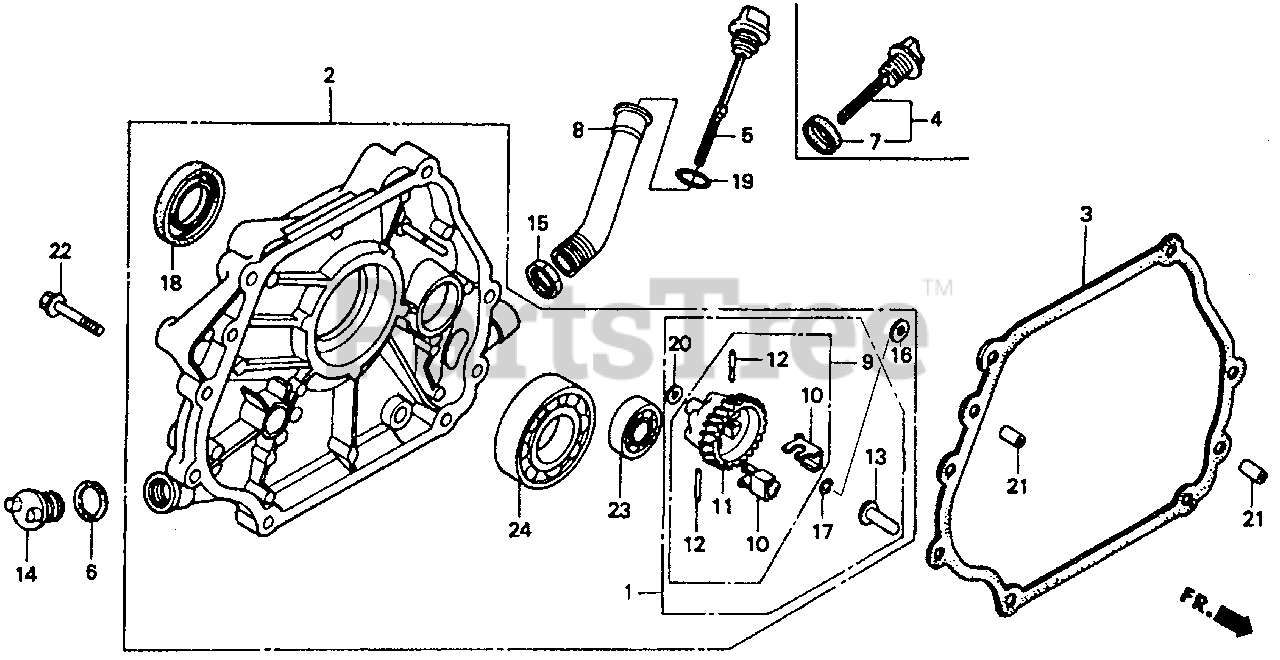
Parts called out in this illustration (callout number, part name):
1	GOVERNOR KIT (BALANCER) (Honda Code 3313665). (NOT AVAILABLE)
1	GOVERNOR KIT (BALANCER)
2	COVER ASSY., CRANKCASE (Honda Code 2025260). (Q-TYPE)(BALANCER)
2	COVER ASSY., CRANKCASE (Honda Code 3689494). (Q-TYPE)(BALANCER)
3	GASKET, CASE COVER
4	CAP ASSY., OIL FILLER
6	GASKET, OIL FILLER CAP
7	GASKET, OIL FILLER CAP
9	GOVERNOR ASSY. (BALANCER)
10	WEIGHT, GOVERNOR
11	HOLDER, GOVERNOR WEIGHT
12	PIN, GOVERNOR WEIGHT
13	SLIDER, GOVERNOR
14	CAP, OIL FILLER
14	CAP, OIL HOLE
15	CAP, OIL FILLER
16	WASHER (6X16)
17	CLIP, GOVERNOR HOLDER
18	OIL SEAL (30X46X8)
20	WASHER, PLAIN (6MM)
21	PIN, DOWEL (8X12)
21	PIN A, DOWEL (8X12)
22	BOLT, FLANGE (8X35)
23	BEARING, RADIAL BALL (6202)
24	BEARING, RADIAL BALL (6206)
